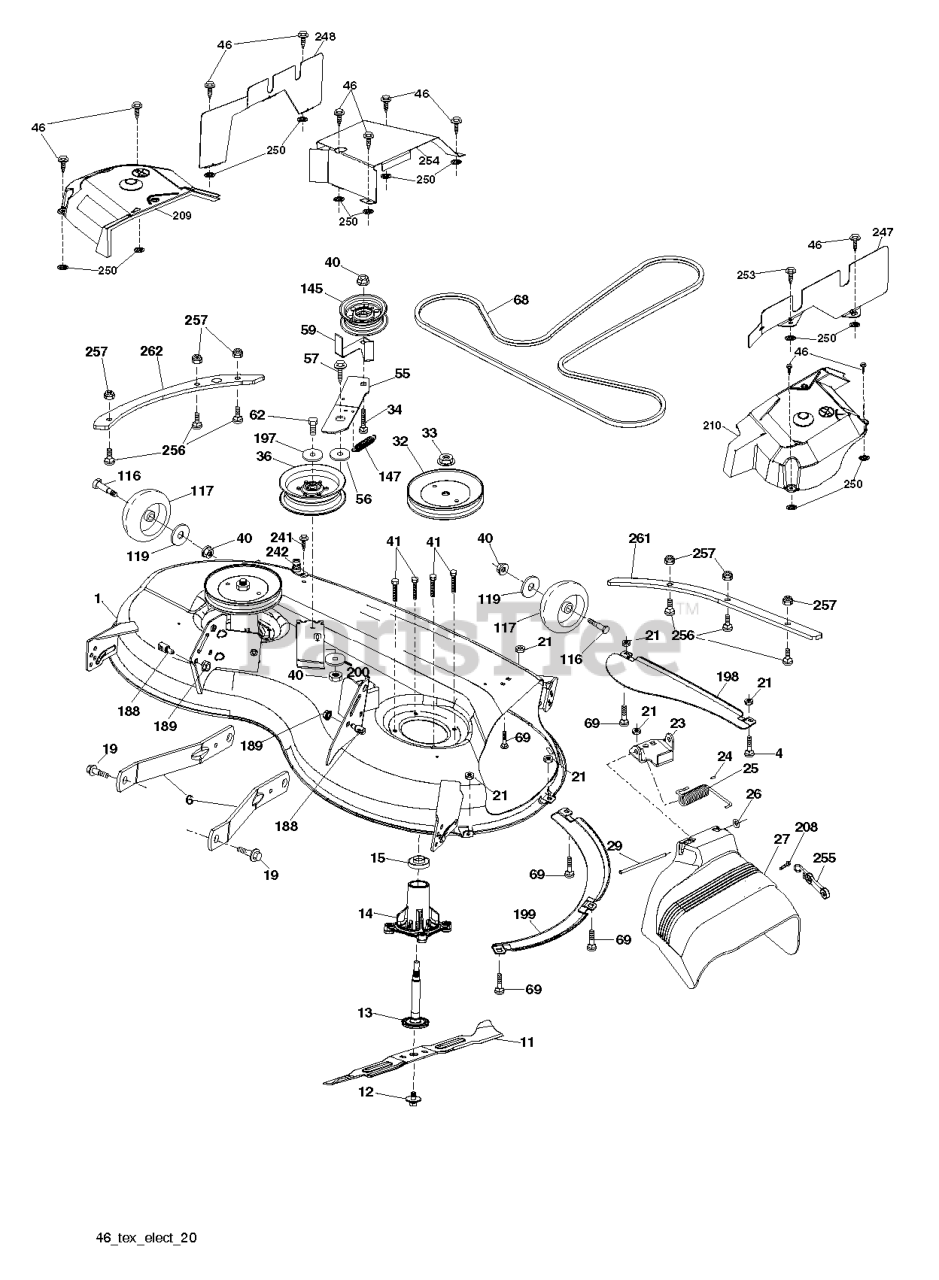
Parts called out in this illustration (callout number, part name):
1	DECK.SVC.WPLATES.46"4GWB.GREY
4	BOLT
6	ARM.SUSPENSION.MOWER.R
11	BLADE.MOWER.46".HI.LIFT
12	SCREW.SEMS.7/16-20X1.HEX.HEAD
13	SHAFT ASM.MNDRL.N/GREASEABLE
14	RP.HOUSING.MANDREL.4PT.
15	BEARING.MANDREL.TOP.EXTENDED
19	BOLT.SHOULDER
21	LOCKNUT
23	BRKT.DEFLECTOR.38"2005+
24	CAP-SLEEVE LT
25	SPRING.TORSION.DEFLECT
26	NUT PUSH M
27	SHIELD SUBASM DEFLECTOR 46 FRE
29	ROD.HINGE
32	PULLEY.MANDREL.5.438.PD
33	NUT.FLANGE.LOCK.TOP
34	BOLT.3/8-16X1.50
36	PULLEY.IDLER.2006
40	NUT LOCK FLG 3/8-16 UNC
41	BOLT.HEX.WASHR.HED.313-18X1.19
46	SCREW.1/4-20X5/8
56	SPACER.RETAINER
57	SCREW 3/8-16X1
59	GUARD, BELT
62	BOLT-HEX EAK
68	V-BELT
69	BOLT
116	BOLT.SHOULDER.3/8-16X3-5/8.
117	WHEEL.GAUGE.RALLY
119	WASHER.5/16.FLAT.STE.STD.
145	PULLEY.IDLER.48"PRIMARY
147	SPRING.MOWER.DRIVE.ELECTRIC
188	STUD.FASTNER.W/ANTI-ROTATE
189	NUT LOCK HEX FLANGE 5/16-18
197	WASHER
198	BAFFLE CENTER FRONT
199	BAFFLE FRONT RH
200	WASHER.13/32 X 1 X 1/2.11GUARD
208	SCREW 3/8-16X1/2
209	COVER.LHS.CE.46CABLE.CLUTCH
210	COVER MANDREL RIGHT
241	SCREW.TT.#10-32X.5.3/8.FLANGE
242	PORT.WASHOUT
247	SHIELD RIGHT
248	SHIELD LEFT
250	PALNUT 1/4
253	SCREW
254	SHIELD REAR
255	ELASTIC STRAP KIT
256	RHSNB, 1/4-20 X 1, GR5
257	NUT T
261	PLATE.REINF.DECK.46".FRONT.BLK
262	PLATE.REINF.DECK.46".SIDE.BLK
